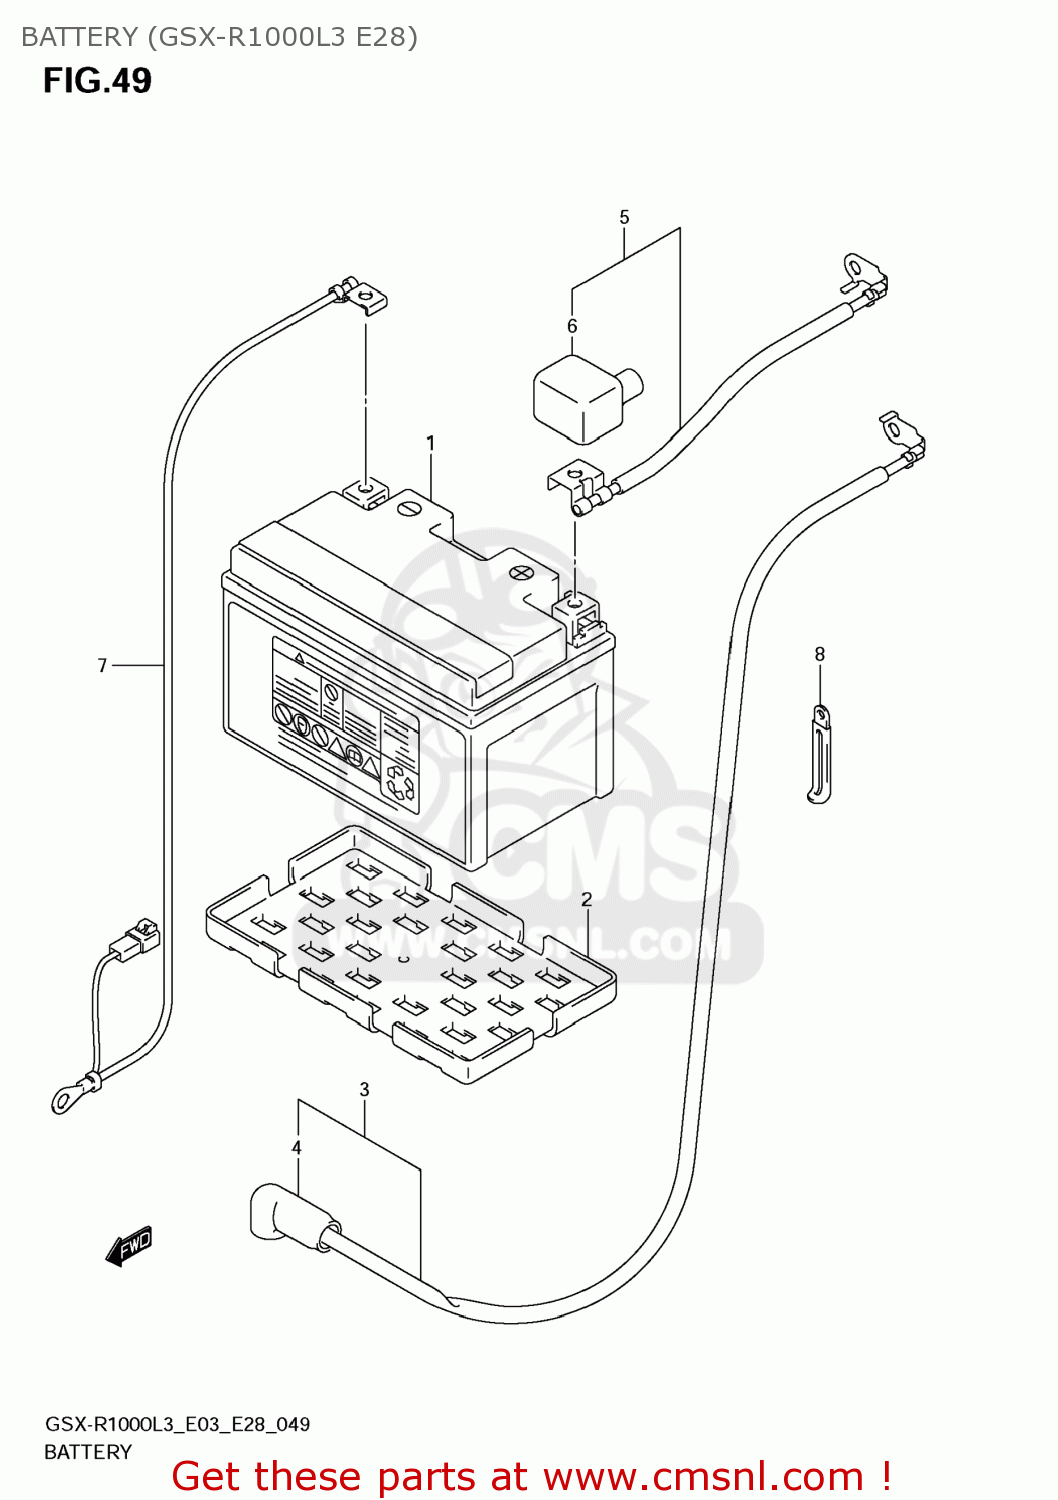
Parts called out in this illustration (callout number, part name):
1	BATTERY ASSY(FT12A-BS,12V10AH)
2	PROTECTOR,BATTERY
3	WIRE,STARTER MOTOR LEAD
4	CAP,OIL PRESSURE SWITCH
5	WIRE,BATTERY PLUS LEAD
6	CAP,BATTERY PLUS
7	WIRE,BATTERY MINUS LEAD
8	CLAMP(L:45)
